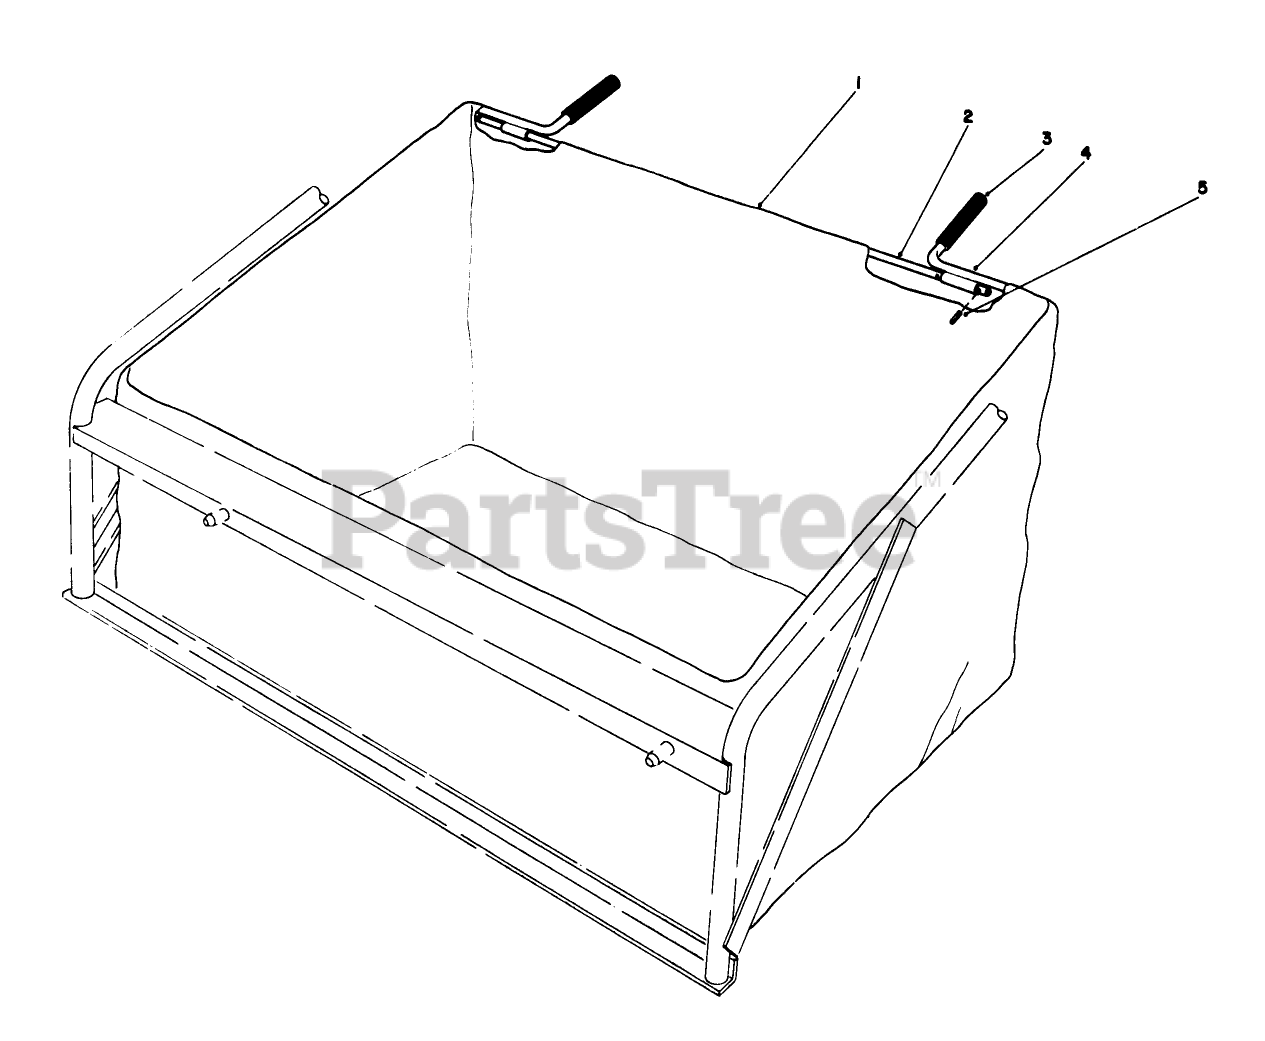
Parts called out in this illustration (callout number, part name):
1	Bag-Leaf Catcher
4	BAG FRAME WA *B
5	PIN-ROLL
